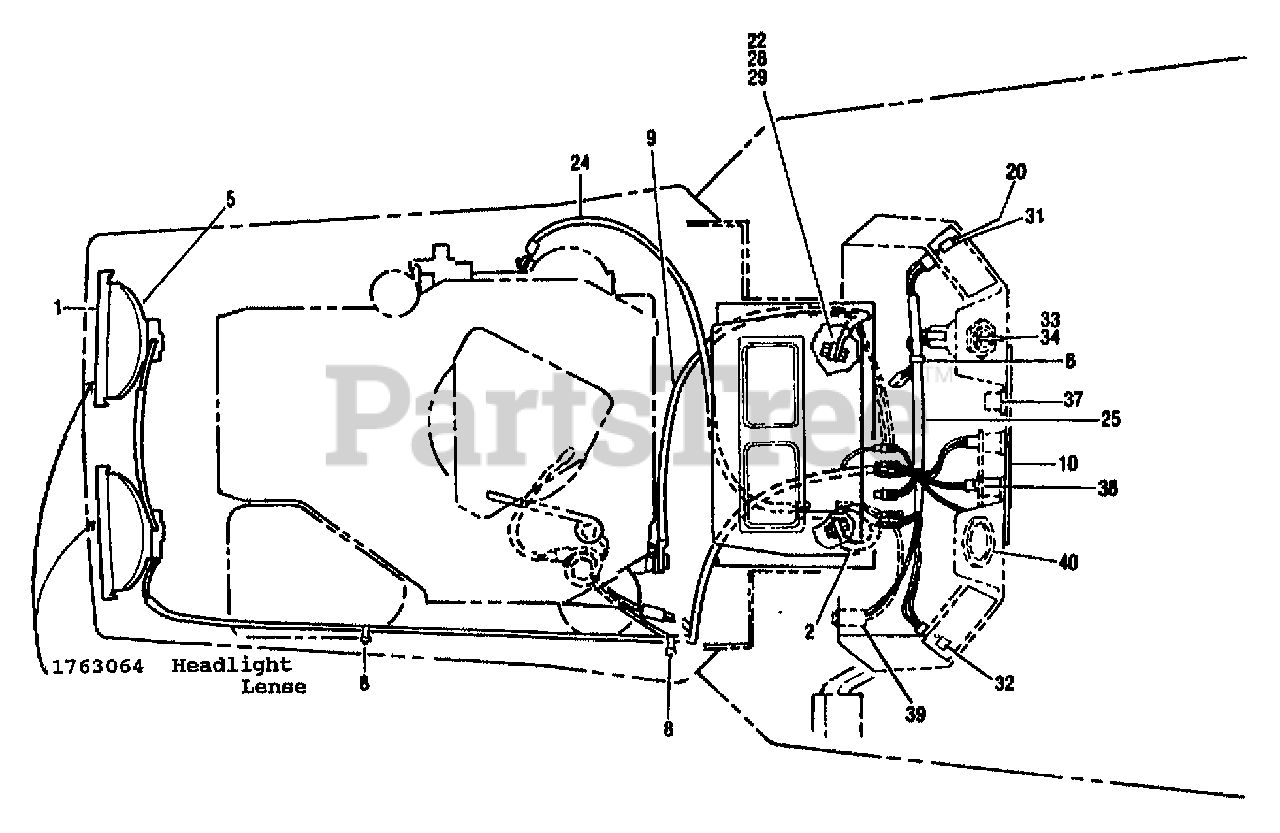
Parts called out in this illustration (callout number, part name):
1	REFLECTOR
2	CABLE-BATTERY (+)
3	LIGHTBULB
4	SOCKET
5	ASSM-LIGHT
8	TIE-CABLE NYLON BLACK
9	CABLE (-)
10	LENSE
13	WASHER-FLAT 1/4 SAE
14	NUT-H/LK 1/4-20
15	BOLT-HOOK
16	SCR-TRUSS #10-24 X 5/8
17	NUT W/LKWASHER 10-24 ZP
18	BATTERY
19	SOLENOID
20	SCR-FHP #6-32X.50 ZP
22	NUT-HEX 1/4-20 ZP
23	GROMMET-SPLIT
24	CABLE-STARTER
25	HARNESS-CONSOLE WIRING
26	CLIP-J
27	TRAY-BATTERY
28	WASHER-LK .25 ZP
29	SCR-HH 1/4-20X.625 G5 ZP
30	HARNESS-INTERLOCK
31	SWITCH-PTO
32	SWITCH-LIGHT
33	SWITCH-IGNITION
34	KEY-IGNITION
35	HARNESS-WIRE ENGINE
36	BATTERY-HOLDDOWN
37	BULB (MFG NO. GE 73)
38	SCR-PHP M6-32X.38 ZP
39	FUSE-30 AMP
43	SCR-PHP 1/4-20X.50 ZP
44	SWITCH-SEAT
46	GROMMET-RUBBER
47	SWITCH
51	SCR-HHS 10-24X.625 ZP
